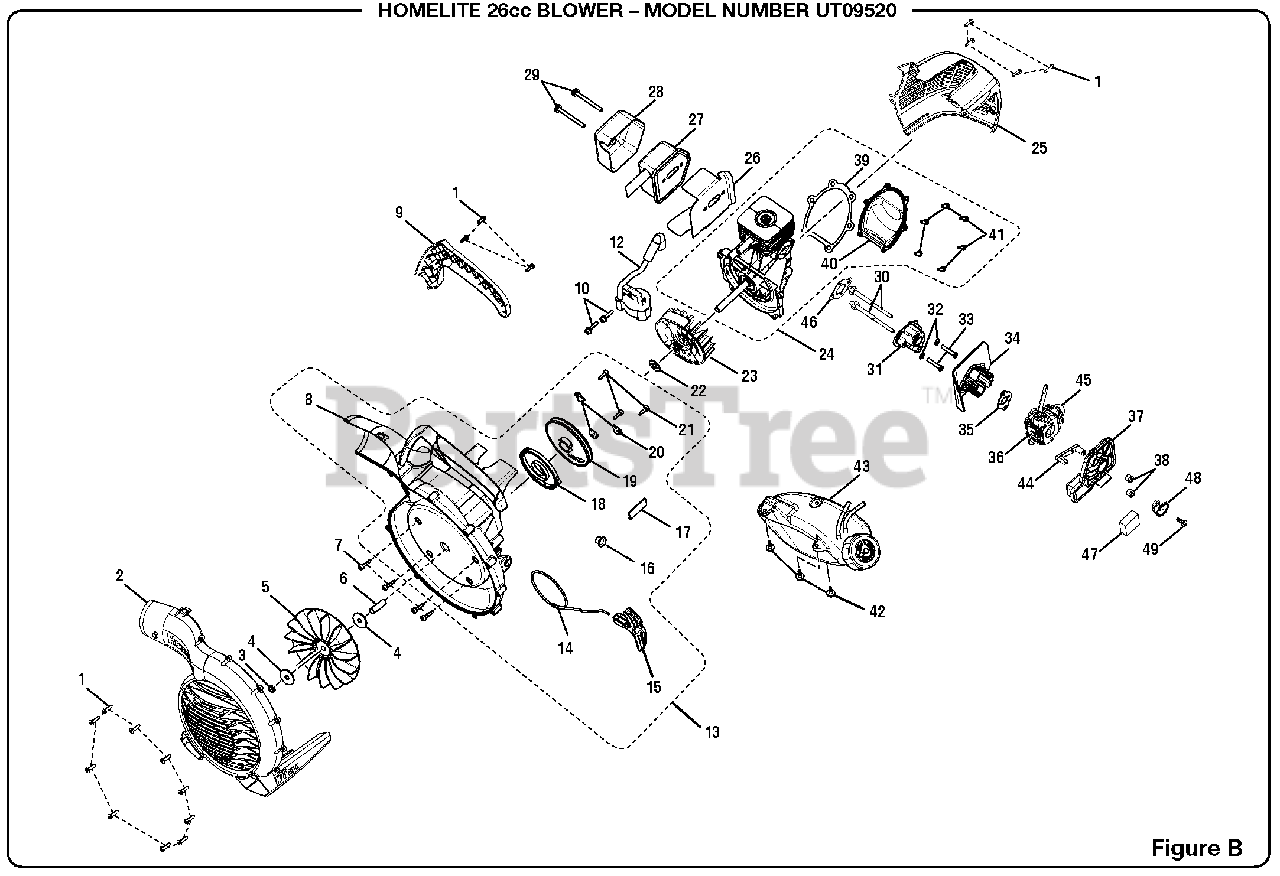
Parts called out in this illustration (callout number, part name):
1	Screw (10-14 x 3/4 in.)
2	Outer Volute
3	Lock Nut (3/8 in.)
5	Fan
7	Screw (M4 x 17 mm, T.F.)
8	Inner Volute
9	Handle Cover
10	Screw (M4 x 19 mm, T.F.)
12	Ignition Module
13	Lower Housing w/Starter Assembly
14	Starter Rope (42 in.)
15	Starter Grip
18	Spring & Container
19	Starter Pulley
20	Pulley Retainer
21	Screw (M4 x 14 mm, T.F.)
22	Washer
23	Rotor and Pawl Assembly
24	Short Block Assembly
25	Engine Cover
26	Muffler Gasket
27	Muffler Assembly
28	Muffler Heat Shield
29	Screw (10-24 x 2-1/8 in.)
30	Screw (10-24 x 2.5 in.)
33	Screw (M5 x 25 mm)
35	Heat Dam Gasket
36	Carburetor
37	Air Box Base
38	Hex Nut (10-24)
39	Crankcase Cover Gasket
40	Crankcase Cover
41	Screw (M4 x 12 mm)
42	Screw (M4 x 16 mm)
43	Fuel Tank Assembly w/Cap
44	Choke Lever
45	Primer Bulb
46	Heat Dam Gasket
48	Choke Cover
49	Screw (M4 x XX mm)
